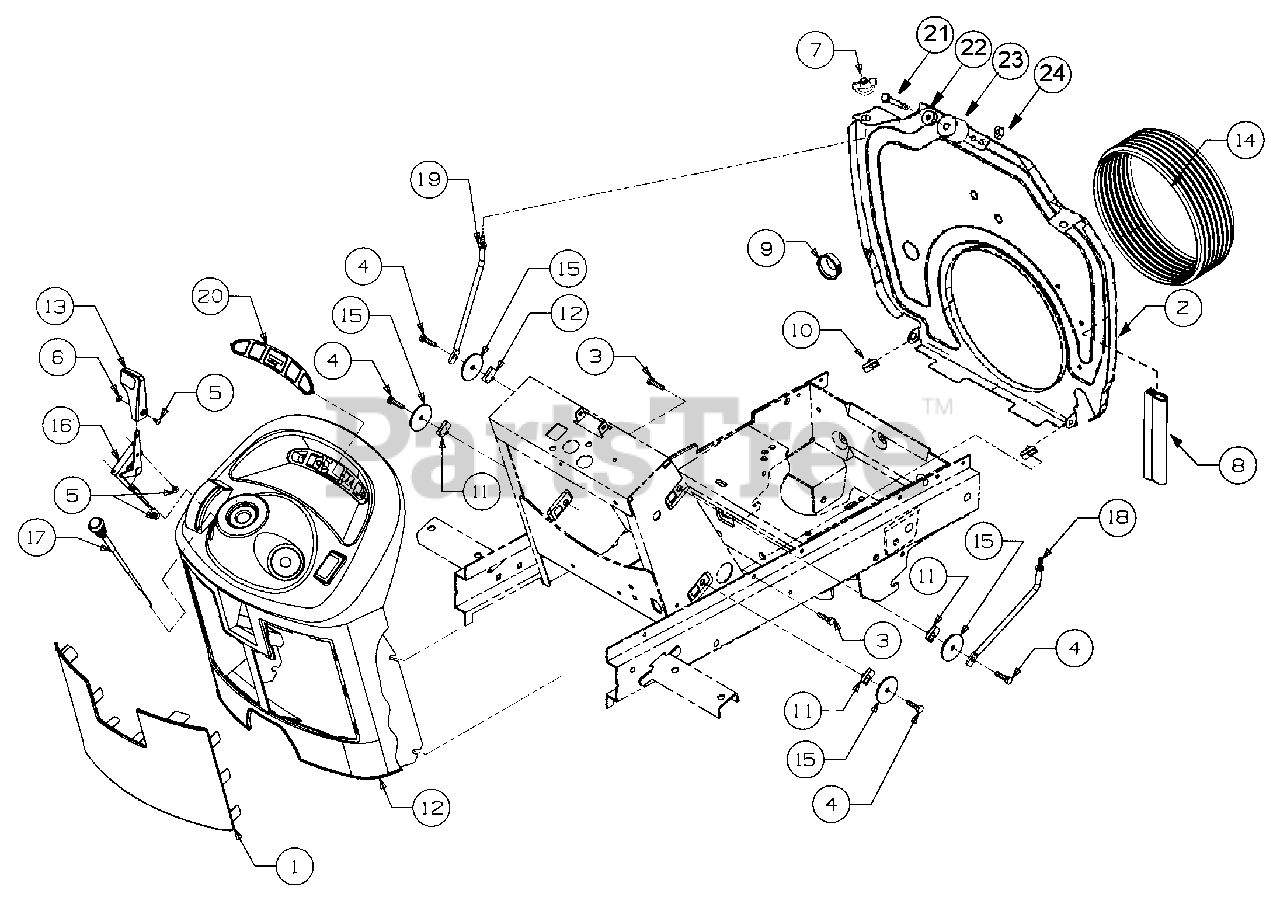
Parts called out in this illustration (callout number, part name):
4	Screw, Hex Cap, 1/4-20 x 1.0
5	Screw, Cross Rec Truss Hd, #8-32 x
6	Nut, #8-32
7	Nut, Wing w/Bell Washer 1/4-20
8	Seal, Push On Trim
9	Bushing, Snap, 7/8 ID
10	Nut, U-Type Speed, 1/4-20
11	Nut, U-Clip, 1/4-20
12	Panel, Dash
13	Knob, Throttle
14	Boot, Intake
15	Washer, Flat, .285 x 1.75 x .10
16	Control, Throttle
17	Control, Choke
18	Rod, RH Mounting
19	Rod, LH Mounting
20	Label, Dash
21	Screw, Hex Cap,1/4-20 x 1.75 GR5
22	Washer, Flat, .283 x .75 x .030
23	Roller, Hood Latch
24	Nut, Hex Sems, 1/4-20
